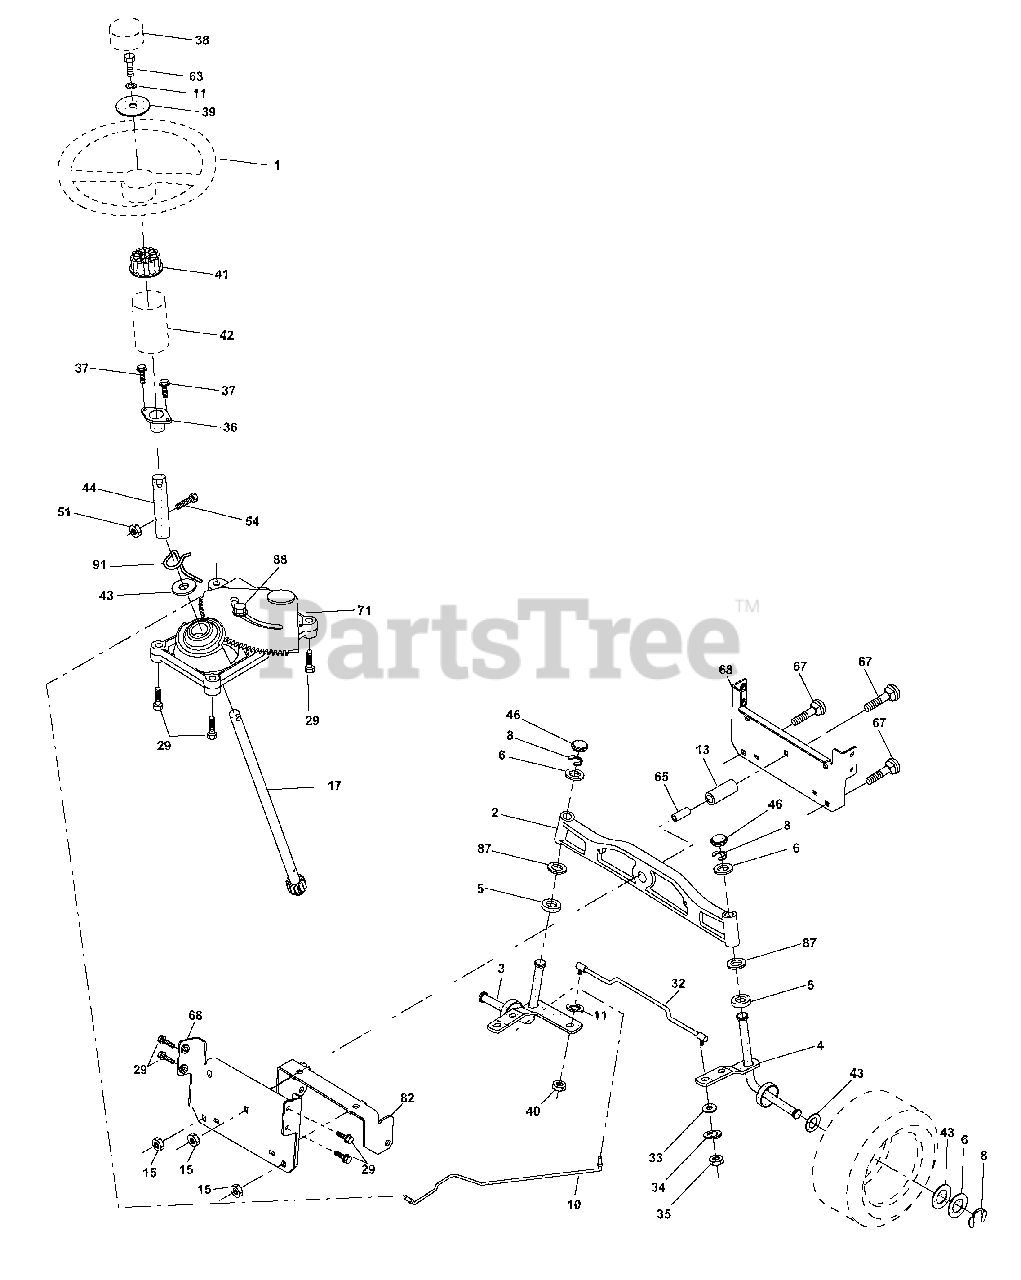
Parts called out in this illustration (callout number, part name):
1	Wheel Steering
2	Axle Asm Cast
3	Spindle Asm LH
4	Spindle Asm RH
5	Bearing Race Thrust Harden
6	Washer 25/32 X 1-5/8 X 16 Ga
8	Ring Klip #t5304-75
10	Link Drag
11	Washer Lock Hvy Hlcl Spr 3/8
13	Spacer Brg. Axle Front
15	Nut Hex Flange Lock
17	Shaft Asm Strg
29	Screw 3/8-16x.75
32	Rod Tie
33	Washer 11/32 x 3/4 x 16 Ga.
34	Washer Lock Hvy Hlcl Spr 5/16
35	Crownlock Nut 5/16-24
36	Bushing Strg
37	Screw
38	Insert Cap Strg Wh Au
39	Washer 13/32 X 2-3/8 X 12 Ga
40	Lock nut
41	Adaptor Wheel Strg
42	Boot Steering Dash
43	Washer 25/32 X 1 1/4 X 16 Ga
44	Extension Steering Shaft LR/LT
46	Cap Spindle Fr Top Blk
51	Nut Lock Hex w/Ins 5/16-18
54	Bolt Fin Hex 5/16-18 Unc x 1-1/4
63	Bolt Fin Hex 3/8-16unc x 1 Gr. 5
65	Brace Axle
67	Bolt Rdhd Sq 3/8-16 Unc x 2-1/4
68	Axle, Brace
71	Steering Asm.
82	Bracket Susp. Chassis Front
87	Washer Flat .781 x 1-1/2 x .14
88	Bolt Shoulder 7/16-20
91	Clip Steering
